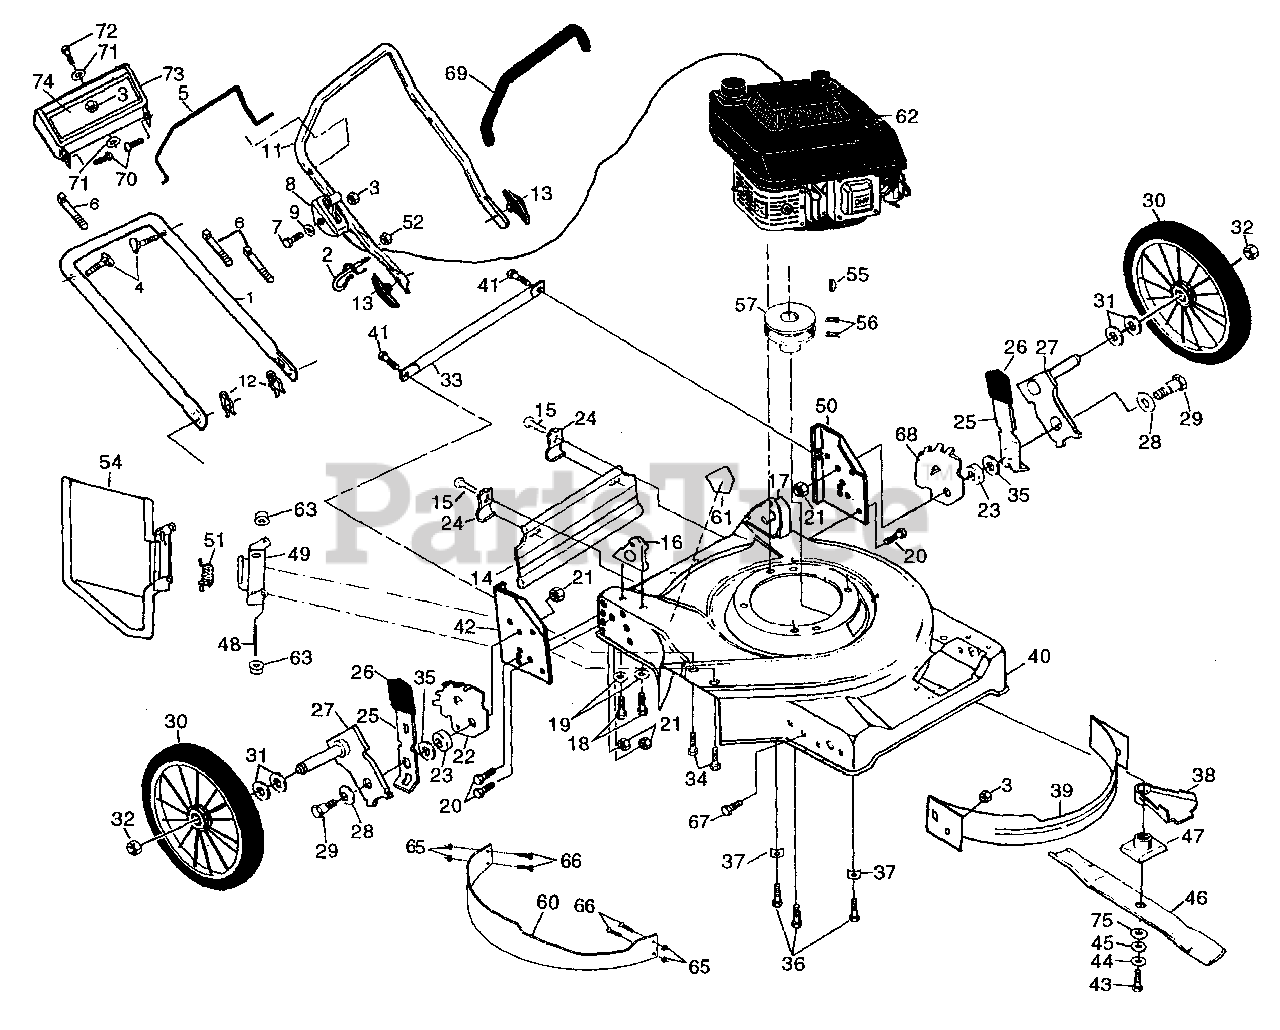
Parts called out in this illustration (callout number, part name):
1	Lower Handle
2	Rope Guide
3	Locknut 1/4-20
4	Handle Bolt
5	Control Bar
6	Wire Tie
7	Machine Screw 1/4-20 x 1/4
8	Throttle Control
11	Upper Handle
12	Hairpin Cotter
13	Handle Knob
14	Rear Skirt
15	Hex Head Screw
16	Handle Bracket Assembly (Right)
17	Handle Bracket Assembly (Left)
18	Screw 5/16-18 x 3/4
20	Hex Head Bolt 3/8-16 x 3/4
21	Locknut 3/8-16
22	Wheel Adjusting Bracket LF/RR
23	Spacer
24	Skirt Bracket
25	Selector Spring
26	Selector Knob
27	Axle Arm Assembly
28	Spring Washer
29	Shoulder Bolt 3/8-16
30	Wheel & Tire Assembly (Rear)
31	Wave Washer
32	Nut
33	Rod Support
34	Hex Head Thread Rolling Screw w/Sems 1/4-20 x 3
35	Flat Washer 3/8
36	Thread Rolling Screw 3/8-16 x 1
37	Engine Washer
38	Debris Shield
39	Front Baffle
40	Mower Housing Kit
42	Wheel Support Bracket R.H.
43	Hex Head Screw 3/8-24 x 1-3/8 Gr. 8
44	Helical Washer 3/8
45	Hardened Washer
47	Blade Adapter
48	Hinge Rod
49	Housing Bracket
50	Wheel Support Bracket L.H.
51	Torsion Spring
52	Locknut 1/4-20
54	Discharge Guard
55	Hi-Pro Key
57	Engine Pulley
60	Mulcher Baffle
61	Danger Decal
62	Engine - Kawasaki
65	Hex Locknut #10-24
66	Machine Screw #10-24 x 1/2
68	Wheel Adjusting Bracket LR/RF
69	Foam Grip
72	Screw
75	Washer
